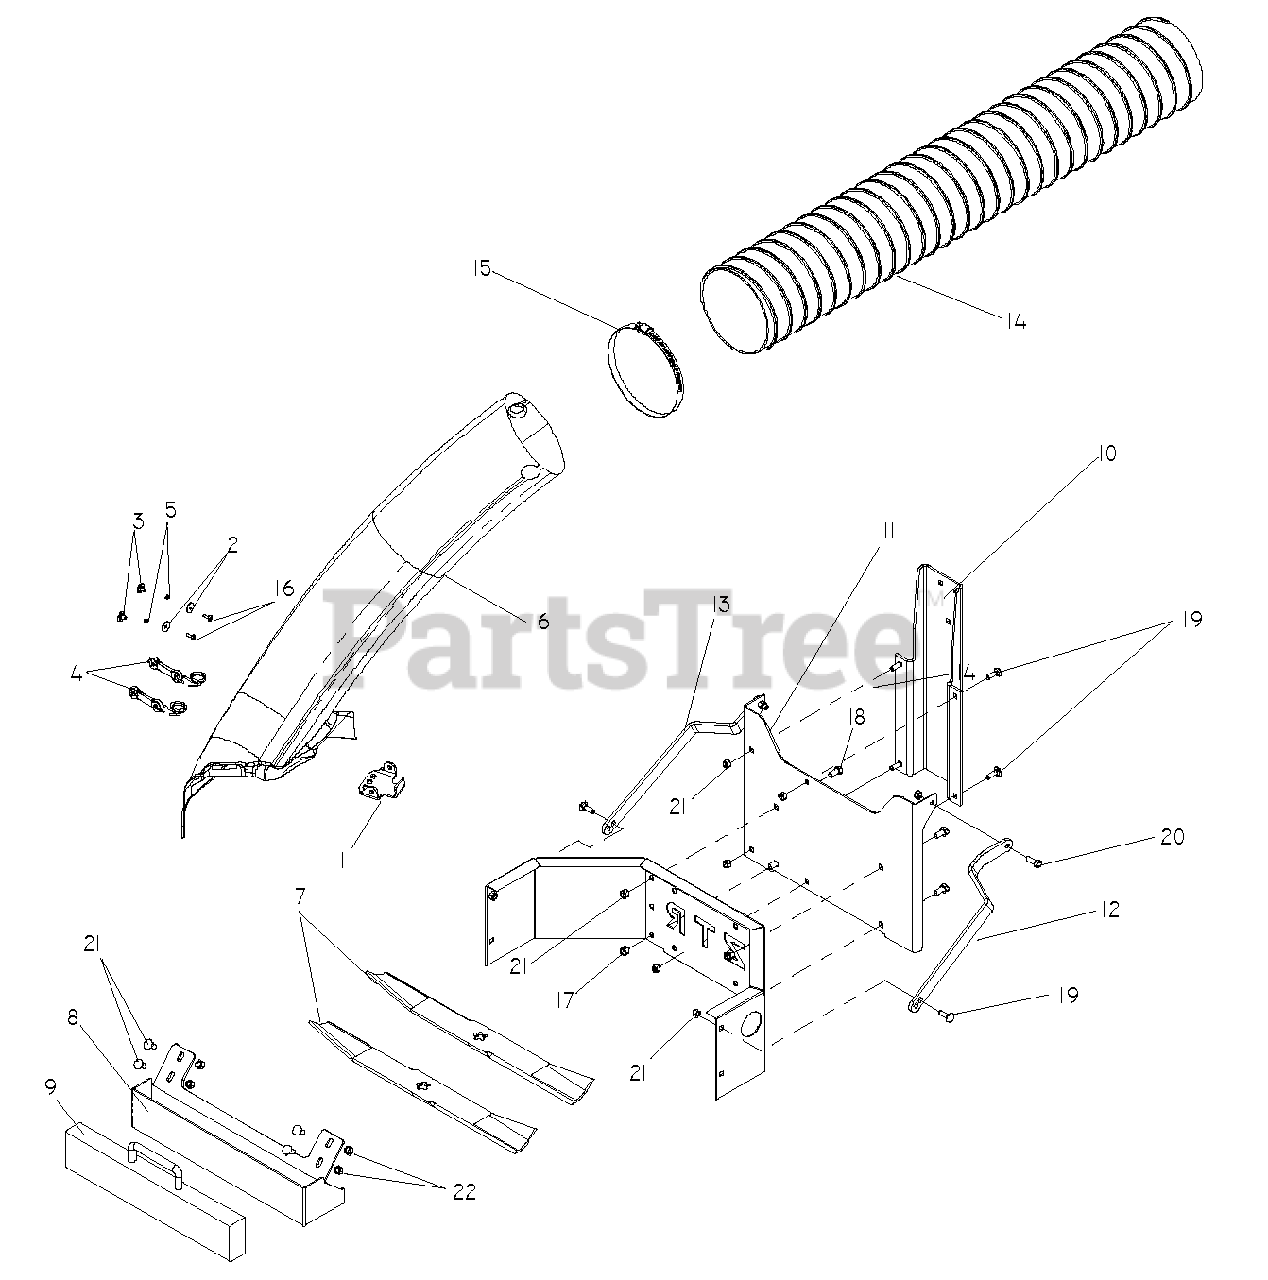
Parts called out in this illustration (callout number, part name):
1	BRKT.DEFLECTOR.38"2005+
3	NUT 10-24 WELD PLATED
4	LATCH ASSY TBR
5	WASHER - 3/16 LOCK ZD
6	LOWER BOOT 42
7	BLD 42` HI LIFT FUS
8	WEIGHT KIT BRACKET WLDT
9	WEIGHT WLDT. RAM
10	BRACKET, HANGER
11	SUPPORT - BAGGER
12	SUPPORT STRAP - L.H.
13	SUPPORT STRAP - R.H.
14	HOSE, 6-3/4 I.D. X 44
16	SCREW #10-24 X 5/8
17	NUT 3/8-16 NYLOC
18	SCREW 3/8C X 3/4 HEX CAP
19	RHSNB 5/16C X 1
20	HCS 5/16C X 1
21	NUT 5/16 NYLOC
22	BOLT 5/16C X 3/4" CARRIAGE
